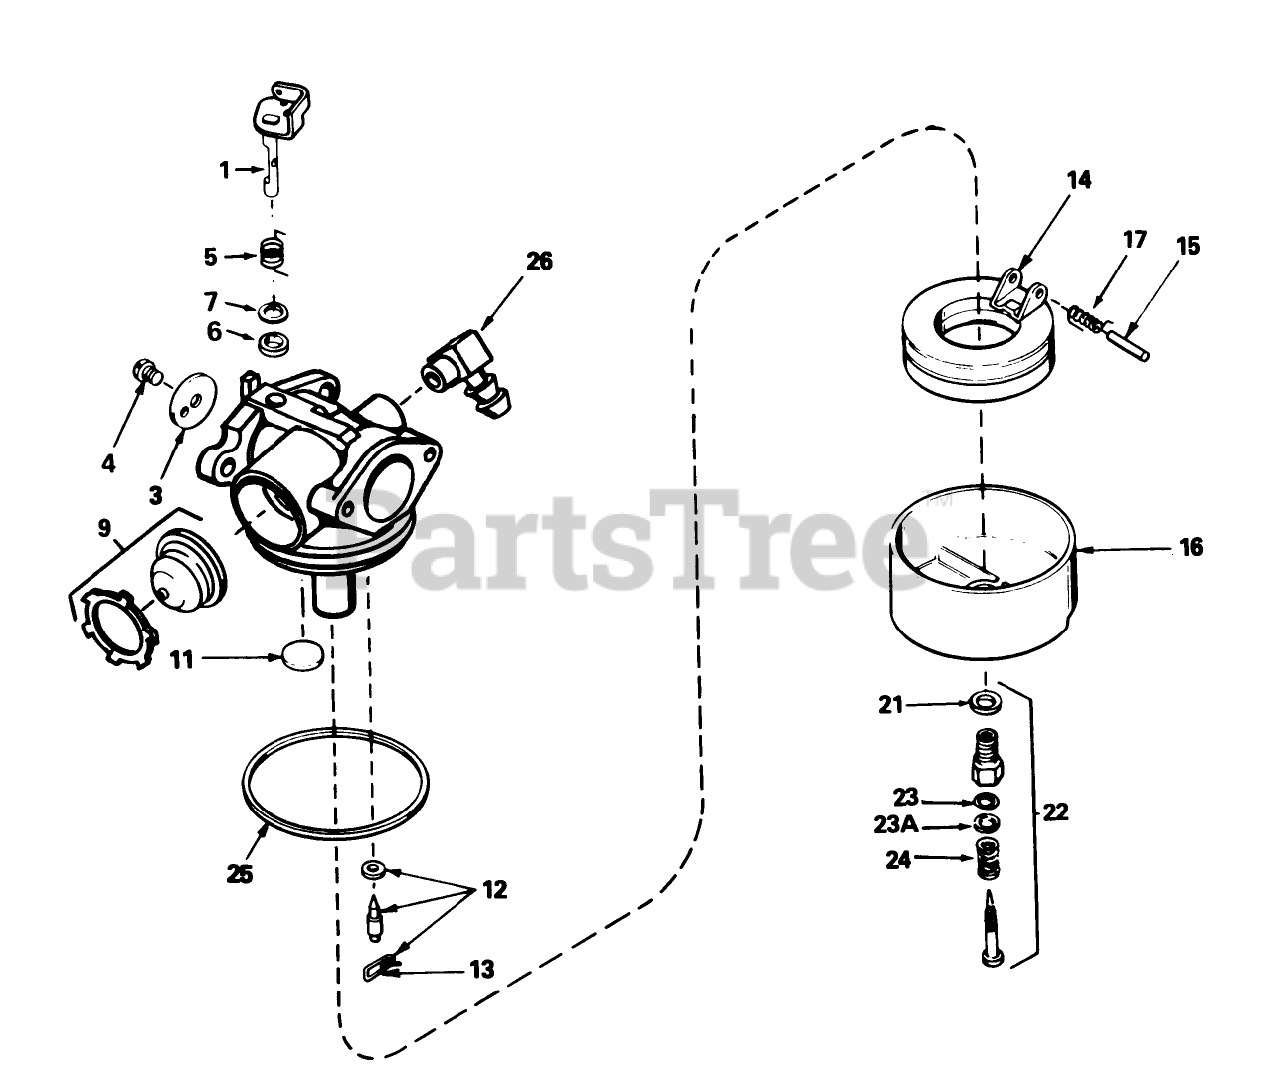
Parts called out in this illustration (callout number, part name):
1	Shaft/Lever Throttle
3	Shutter-Throttle
4	Screw-Shutter
5	Spring-Trottle, Return
6	Seal-Dust
7	Washer-Seal, Dust
9	Bulb-Primer
11	Plug-Welch, Atmospheric Vent
12	Inlet Needle, Seat Clip Assy. (Incl. No. 13)
13	Clip-Spring
14	Float
15	Shaft-Float
16	Bowl-Float (no drain)
17	Spring-Float, Dampening
21	Washer-Bowl Nut
22	Adjustment Screw Assembly, Main (Incl. Nos. 5A, 21, 23 27)
23	ORing
23A	Washer
24	Spring
25	O Ring-Bowl, Float
26	Fitting-Fuel
